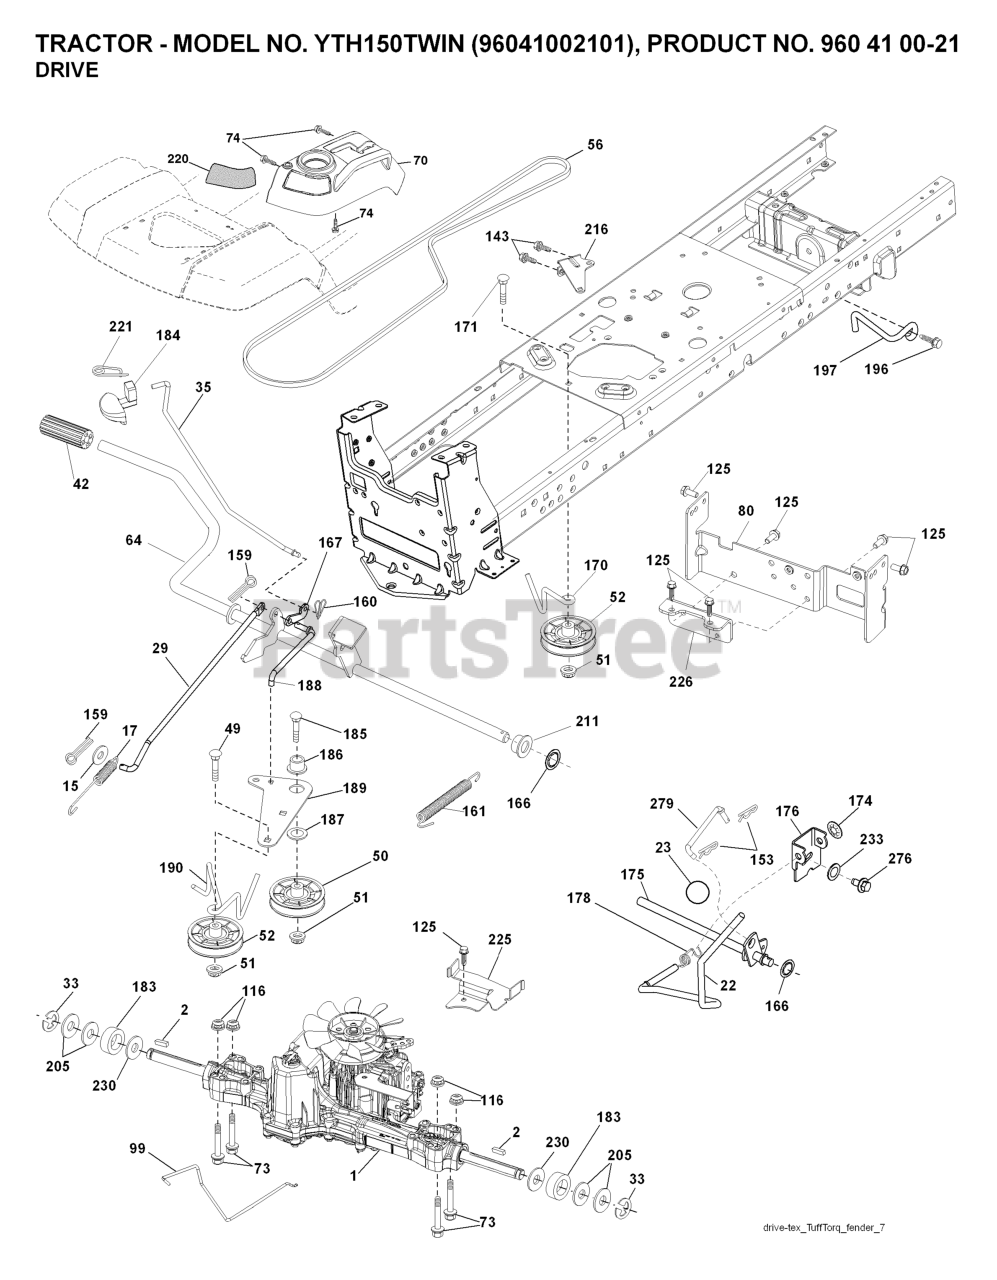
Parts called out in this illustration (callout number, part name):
1	TRANSAXLE.K46A.18/20"F
2	SQUARE KEY
15	WASHER
17	SPRING.BRAKE.K46.GREEN
22	ROD.SHIFT.FENDER.STGT.
23	KNOB.DUCKHEAD.1/2
29	ROD.BRAKE.K46
35	ROD.BRAKE.PARKING.GT.H
42	PEDAL COVER T
50	IDLER.FLAT.910.OFFSET
51	NUT LOCK FLG 3/8-16 UNC
52	IDLER.V-GROOVE.910.OFFSET
56	V-BELT.MOWER.92.40.42/K46
64	SHAFT.ASM.PEDAL.BRAKE.
70	RP CONSOLE.ASM.HYDO.HUSQ.
73	BOLT HEX 5/16-18 GR 5
74	SCREW.HI-LO.CONSOLE
80	STRAP TORQUE
99	ROD ASM BYPASS
116	NUT LOCK HEX FLANGE 5/16-18
125	SCREW
143	Screw 5/16-18 x 1/2 Hex, Self Tapping 5/16-18 x 1/2
153	RETAINER M
159	COTTER PIN
160	RETAINER CLIP
161	SPRING, RETURN LT
166	NUT.PUSH.625.2006
167	LATCH.BRAKE.SPRING
170	KEEPER.V-IDLER.CENTER.
174	NUT.PUSH.500.2006
175	SHAFT ASM SHIFT
176	ARM.CLEVIS.ROD.SHIFT
178	SPRING.SHIFT.GT2006
183	SPACER AXLE
184	HANDLE.PARKG.BRK.HUSQ X667
186	SPACER.RETAINER
187	WASHER 12/32X2X10GA
188	RP.LINK.CLUTCH.GROUND.DRIVE
189	BELLCRANK.GROUND.DRIVE.TEX.
190	KEEPER.BELLCRANK.DRIVE
196	SCREW 3/8-16X1
197	LINK.CLUTCH.ANIT-ROTAT
211	BUSHING.SHAFT.BRAKE.HAND
216	BRACKET.PULLEY.IDLER.W/TEX
221	RETAINER.SPRING.CLIP.H
225	KEEPER.BELT.TRANSAXLE.K46
226	BRACKET.MOUNT.TORQUE.K46.TLT
230	WASHER.HARDENED
233	WASHER SERRATED
276	BOLT FIN HEX 7/16-14 X 1
279	LINK.SHIFT.T/A.K46.FEND.TX
